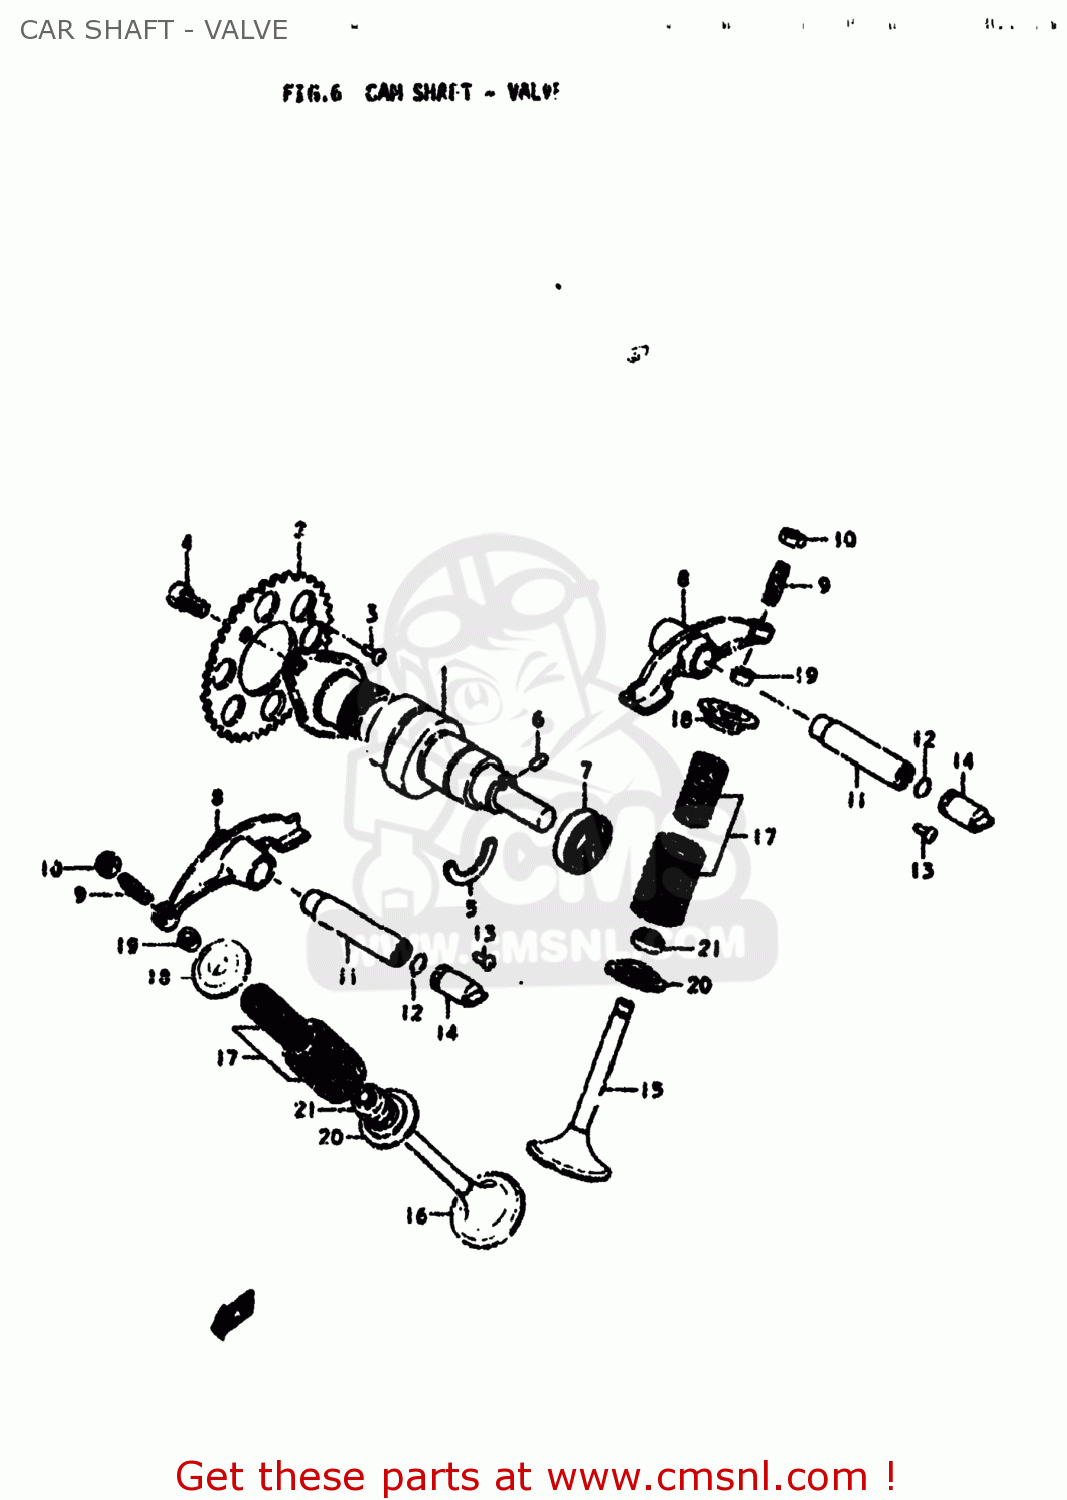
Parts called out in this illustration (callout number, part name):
1	CAMSHAFT
2	SPROCKET,CAMSHAFT
3	SCREW 5X6
4	BOLT 6X11
5	C RING
6	PIN 3X5
7	OIL SEAL (18X30X7)
8	ARM,VALVE ROCKER
9	SCREW,TAPPET ADJUSTING
10	NUT,ADJUSTING SCREW
11	SHAFT,VALVE ROCKER
12	O-RING
13	SCREW
14	CAP,ROCKER ARM SHAFT
15	VALVE,INTAKE
16	VALVE,EXHAUST
17	SHIM,TAPPET
18	RETAINER,VALVE SPRING
19	SHIM,TAPPET
20	SEAT,VALVE SPRING
21	SEAL,OIL(7X14.4X9)
